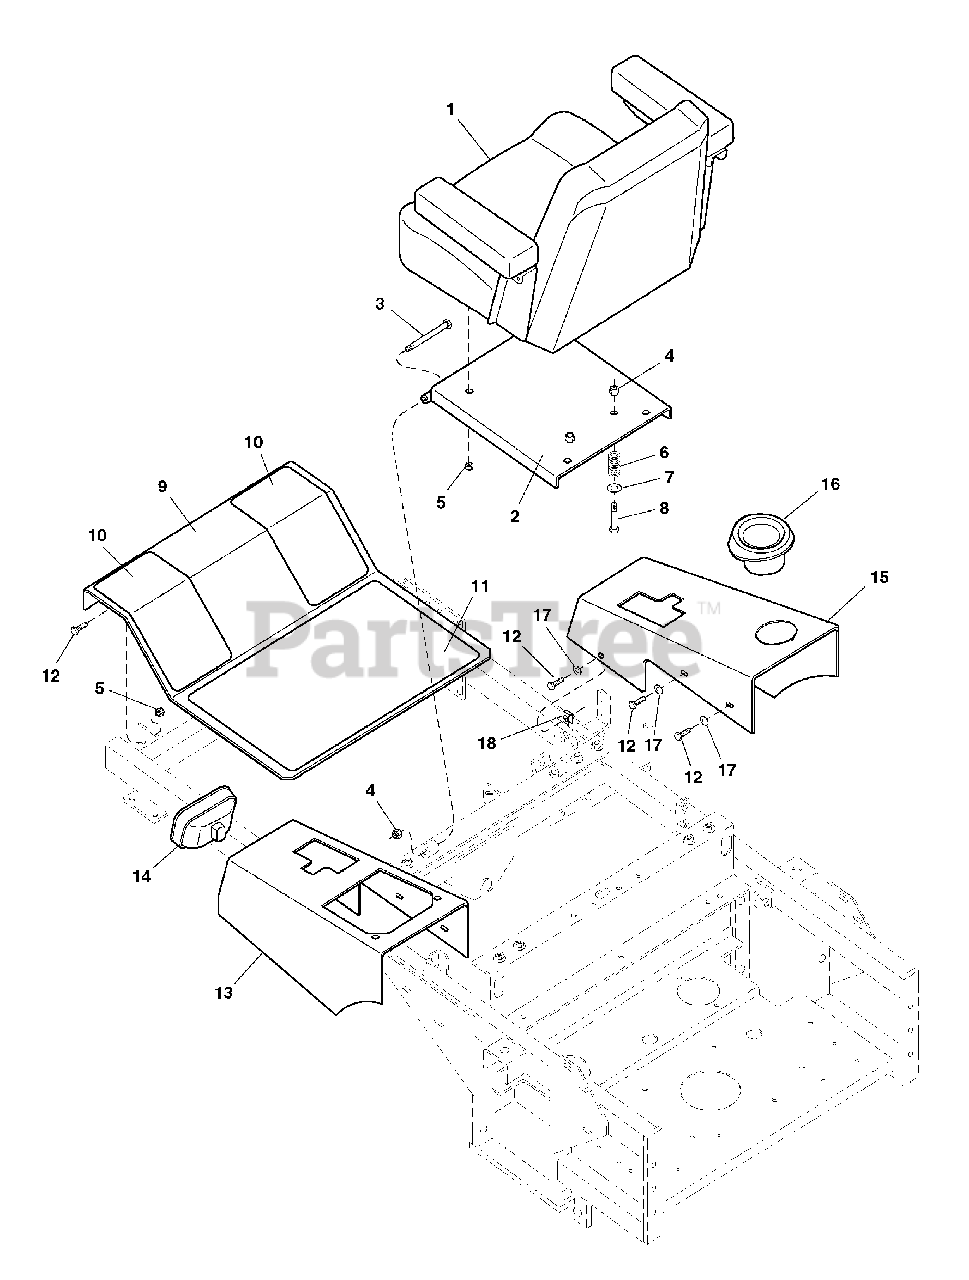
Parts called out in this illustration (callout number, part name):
1	SEAT, Brown (complete)
2	PLATE, Seat Mount
3	CAPSCREW, Hex Hd, 3/8-16 x 4
4	NUT, Hex, Nylon Lock, 3/8-16
5	NUT, Hex, Nylon Lock, 5/16-18
6	SPRING, Compression
7	WASHER, 3/8
8	CAPSCREW, Hex Hd, 3/8-16 x 2-1/4
9	FLOOR
10	SAFETY WALK
11	SAFETY WALK
12	CAPSCREW, Hex Hd, 5/16-18 x 1
13	CONTROL COVER, LH
14	HEADLIGHT ASSEMBLY, Complete
15	CONTROL COVER, RH
17	WASHER, 5/16
18	BODY CLIP, 5/16-18
